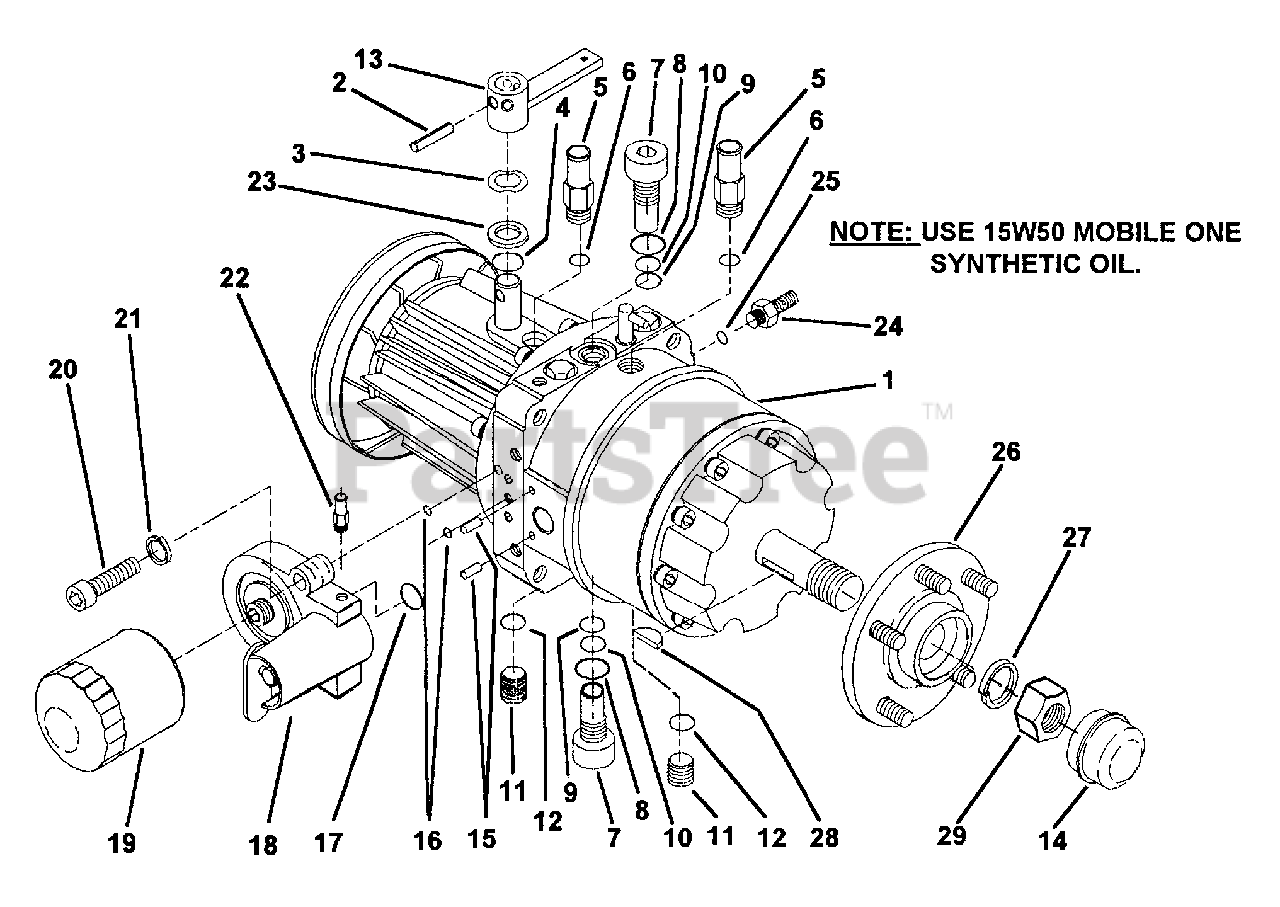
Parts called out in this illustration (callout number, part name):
1	UNISTAT TRANSMISSION ASSEMBLY, R.H.
2	ROLL PIN, 5/16" OD X 1-1/4 LONG
3	WASHER, WAVE SPRING: STAINLESS
4	O-RING,.734 ID X .139 W
5	FITTING, 5/8 HOSE 3/4-16, (comes with o-ring)
6	O-RING, .644 ID X .087 W, VITON
7	HI-PRESSURE, RELIEF VALVE ASSEMBLY, HI-CAP
8	O-RING, .924 ID X.1 16 W, VITON
9	O-RING, .671 ID X.1 39 W, VITON
10	BACK-UP RING
11	PLUG O-RING: 3/4-16 (comes with o-ring)
12	O-RING,.644 ID X .087 W, VITON
13	SHIFT ARM WELDMENT
14	GREASE CAP 2" ID X 3/8 DP
15	DOWEL PIN 1/4 X 1/2 LG
16	O-RING, VITON: .301 ID X .070 W
17	O-RING, VITON: 1.301 ID X .070 W
18	FILTER BLOCK ASSEMBLY, R.H.
19	OIL FILTER 3" OD X 3-11/32 H (NAPA 1045)
20	SOCKET HEAD CAP SCREW 1/2"-13 X 2"
21	LOCK WASHER, 1/2" STANDARD SPLIT
22	FITTING, 1/8 NPT X 3/8 HOSE
23	WASHER, SS:.781 X 1.137 X 18 GA
24	MOUNTING PLUG ASSEMBLY, (comes with o-ring)
25	O-RING,.486 ID X.078W, VITON
26	WHEEL, HUB, 5-BOLT UNISTAT
27	LOCK WASHER, 1" SPLIT GAL.
28	KEY, WDRF. USAS 808 1 /4" X 1 ", #15
29	HEX NUT, 1 "-14 NF, PLATED
